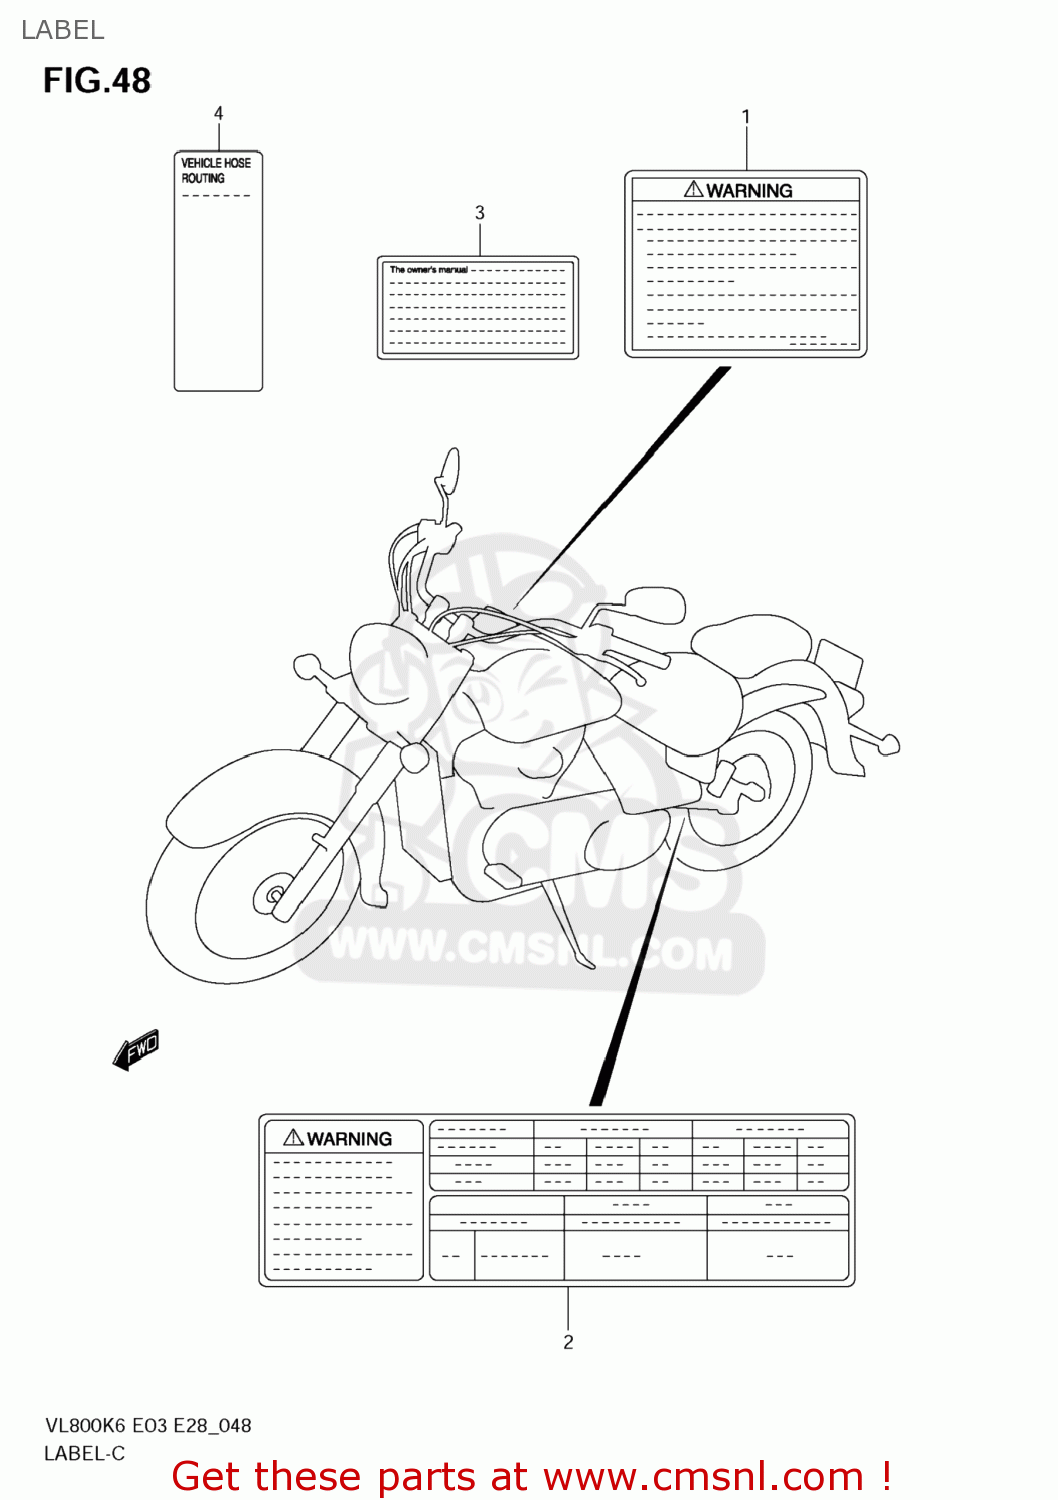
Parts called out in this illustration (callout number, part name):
1	LABEL,GENERAL WARNING
2	LABEL,TIRE INFORMATION
3	LABEL,MANUAL NOTICE
4	LABEL,VACUUM HOSE ROUTING
5	MANUAL,OWNER'S
